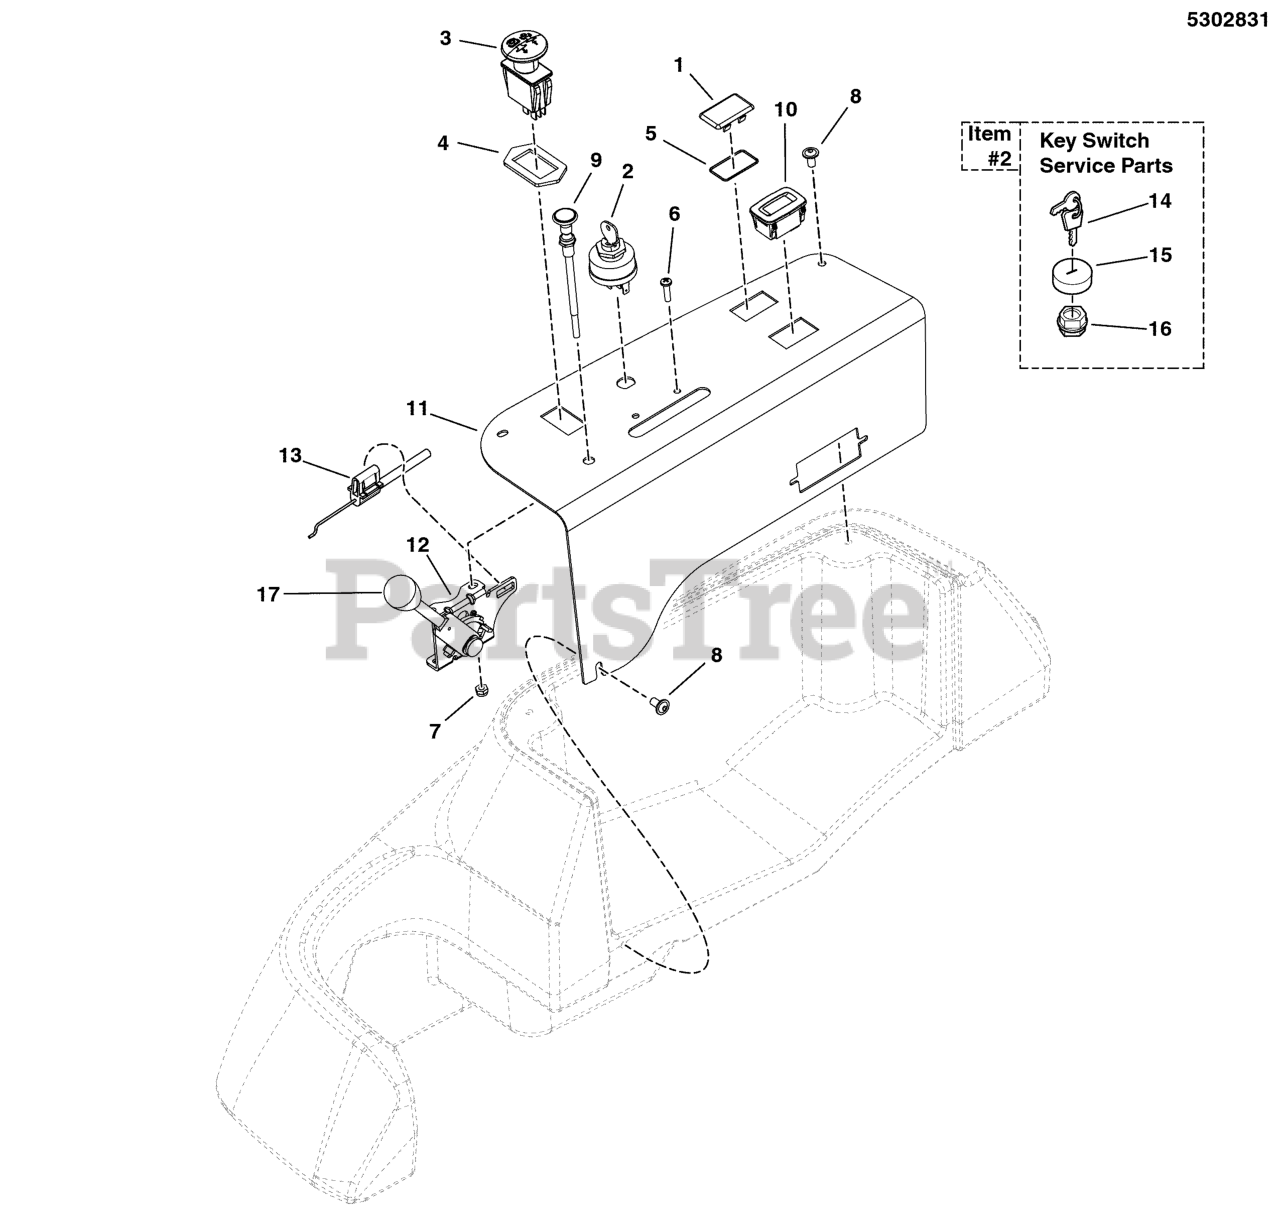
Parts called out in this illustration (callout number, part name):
1	PLUG, .820X1.44 HOLE, BLACK PLASTIC
2	SWITCH, IGNITION, 6 POST
3	SWITCH, BLADE ENGAGEMENT
4	RING, SWITCH RETAINER
5	O-RING, 7/8" ID X 1/16" W
6	SCREW, #10-24 X 3/4" ROUND PHILLIPS
7	NUT, Hex, Nylon Lock, #10-24
8	SCREW, ALLEN HEAD 1/4-20X.500 ZINC PHOS
9	CABLE, CHOKE CONTROL, 43.5"
10	HOUR METER, ASSEMBLE
10	HOUR METER
11	PLATE, CONTROL PANEL - BLK
12	LEVER, THROTTLE CONTROL, HEAVY-DUTY
13	CABLE, THROTTLE, 42"
14	KEY, IGNITION MOLDED SET
15	COVER, PLASTIC, SNAP ON
16	PLASTIC NUT
17	THROTTLE CONTROL HANDLE/KNOB
